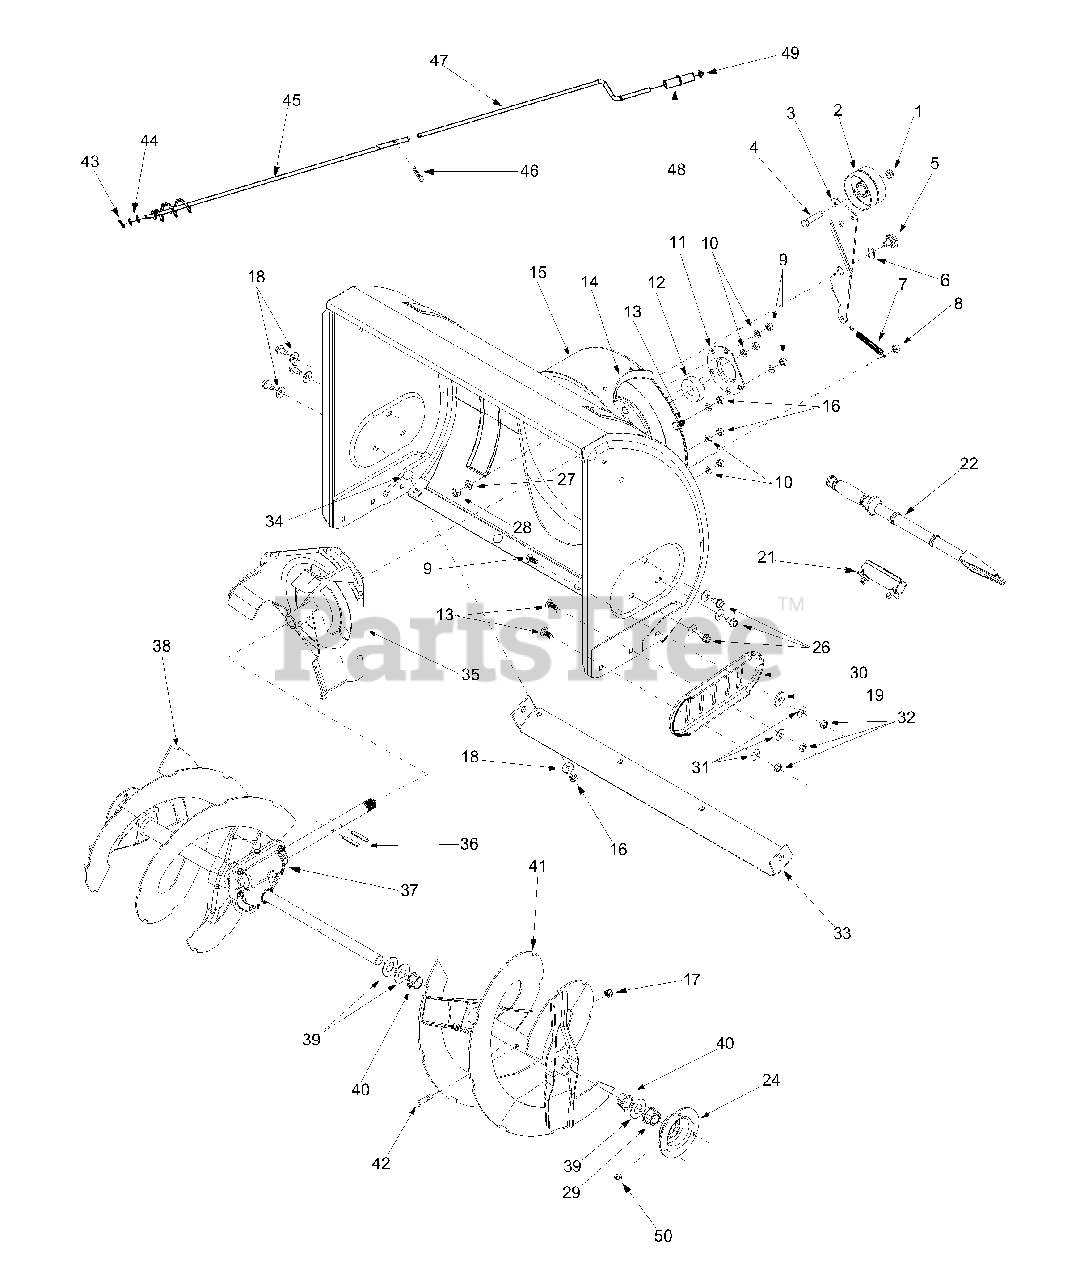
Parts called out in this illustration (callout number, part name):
1	Lock Jam Nut 3/8-24
2	Flat Idler
4	Hex Cap Screw 3/8-24 x 1.50
5	Shoulder Screw
6	Flat Washer .656 ID x 1.25 OD
7	Extension Spring
8	Hex Nut 5/16-18
9	Carriage Bolt, 5/16-18 x 1.00
10	Lock Washer 5/16
12	Ball Bearing
13	Carriage Bolt, 5/16-18 x .75
17	Lock Nut 5/16-18
18	Belleville Washer
19	Flat Wshr, .344ID x 1.125 OD
21	Clean-Out Tool Mount
22	Clean-Out Tool
26	Hex Screw 5/16-18
27	Lock Washer 3/8
28	Hex Nut 3/8-16
29	Hex Flange Bearing
31	Bell Washer
32	Hex Nut 5/16-18
34	Carriage Bolt 5/16-18 x 1.00
37	Gear Assembly Complete, 28"
39	Flat Washer
40	Flange Bushing
42	Shear Bolt 5/16-18 x 1.5
43	Hairpin Clip
44	Flat Washer
48	Chute Crank Knob
50	Crease Fitting
